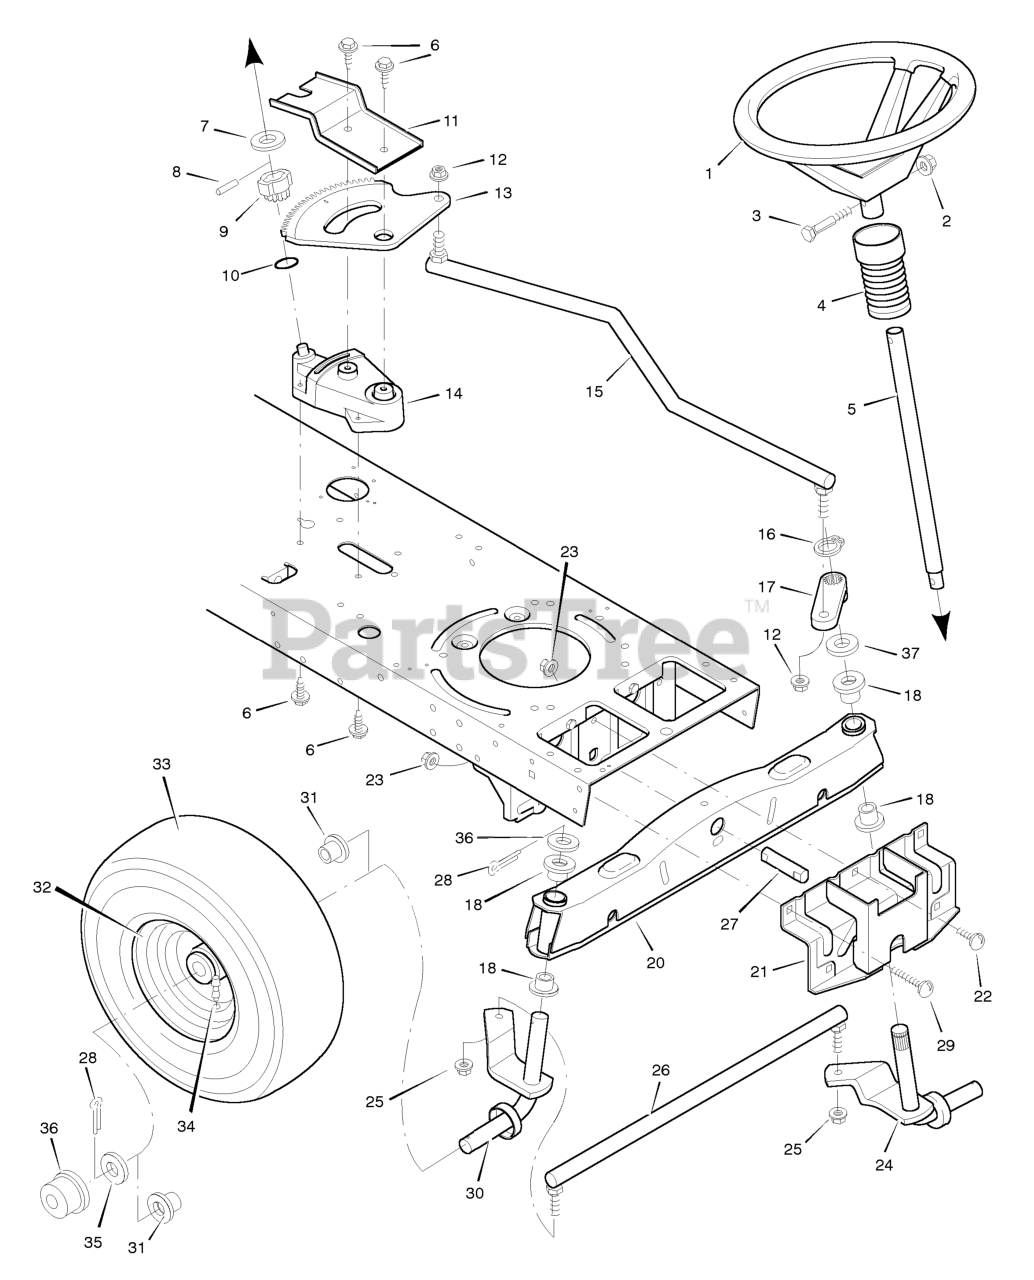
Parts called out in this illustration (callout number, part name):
1	Wheel, Steering
2	Nut, Hex
3	Bolt, Hex
4	Bellows
5	Post Assembly, Steering
7	Washer
8	Pin, Spring
9	Gear Assembly, Pinion
10	O-Ring
11	Clip, Gear Retainer
12	Locknut, Flange
13	Gear, Sector
14	Support, Steering
15	Link, Drag
16	E- Ring
17	Arm, Drag Link
18	Bearing
20	Axle Assembly (with grease fittings)
21	Hanger Assembly, Axle
22	Bolt, Carriage
23	Locknut, Flange
24	Spindle Assembly, Left
25	Locknut, Flange
26	Rod, Tie
27	Pin, Pivot
28	Pin, Cotter
29	Bolt, Carriage
30	Spindle Assembly, Right
31	Bearing, Wheel
32	Wheel & Tire Assembly
33	Tire *
34	Stem, Valve
36	Hub Cap
